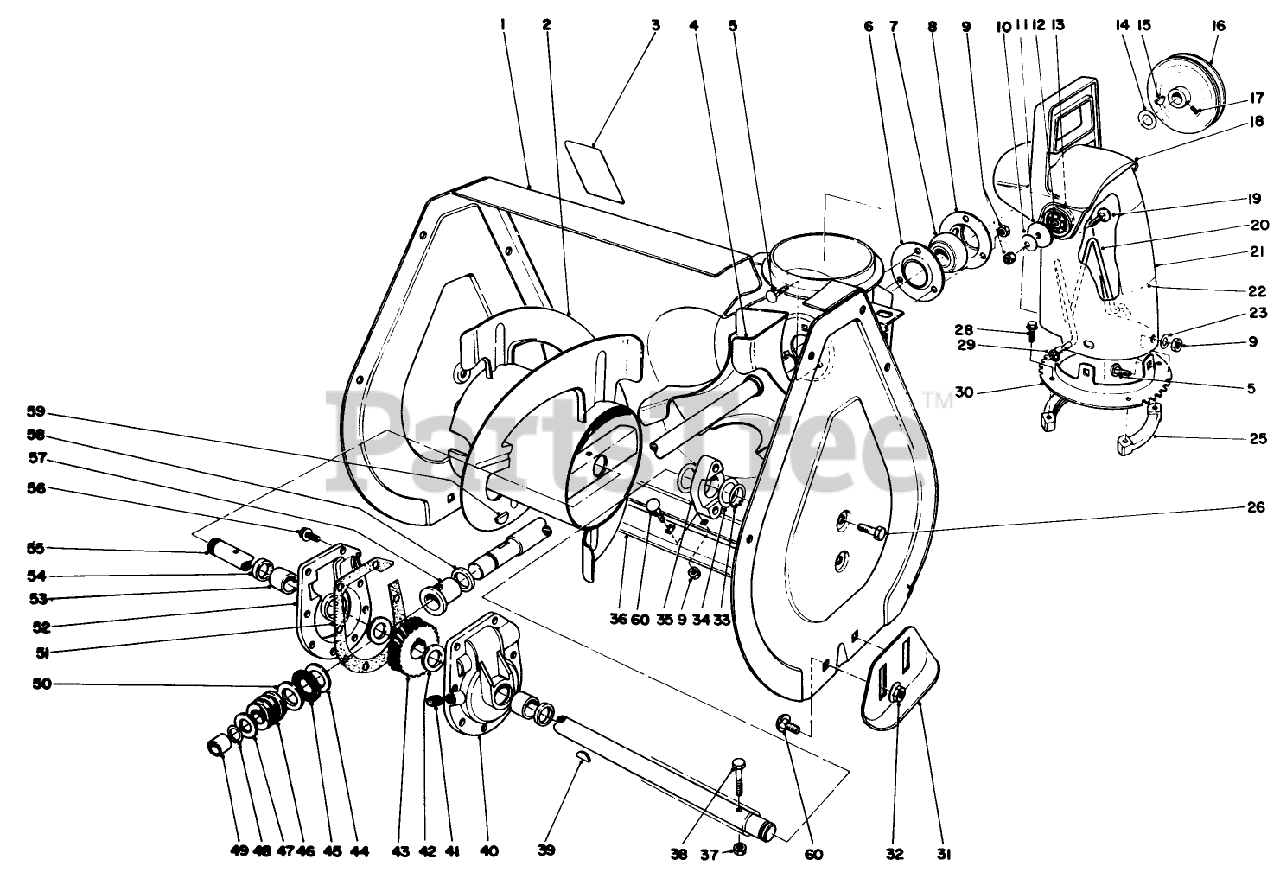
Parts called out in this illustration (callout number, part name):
1	Housing-Auger (Incl. Ref. #3)
2	Auger R.H.
3	DECAL-WARNING, AUGER
4	Shaft & Impeiler
5	SCREW-CARR
6	Flange Bearing-Front
7	BEARING-BALL
8	Flange Bearing-Rear
9	NUT-LOCK, NI
10	WASHER-BELLEVILLE
11	WASHER-FLAT
12	PLATE-FRICTION
13	WASHER-RUBBER
14	WASHER
15	KEY-WOODRUFF
16	PULLEY
17	SCREW-SET, SQH
18	CHUTE-DEFLECTOR
19	SCREW-CARR
20	WIRE-CHUTE
21	Chute Discharge (Incl. Ref. #22) (Model 38052)
21	Chute Discharge (Incl. Ref. #22) (Model 38054)
22	Decal-Danger
22	DECAL-DANGER DISCH.
23	WASHER-PLAIN
25	RING-CHUTE, RETAINER
26	SCREW-HWHTF
28	SCREW-SPECIAL
29	NUT-PUSH
30	Chute Ring
31	Skid
32	NUT-HF
33	RING-RETAINING
34	WASHER
35	BEARING-AUGER
36	Blade-Scraper
37	NUT-LOCK, NI
38	SCREW-HH
39	KEY-WOODRUFF
40	Gear Case-L.H.(Incl. Ref. #53 & 54)
41	PLUG-PIPE, SQH
42	WASHER-THRUST
43	Gear
44	WASHER-THRUST
45	BEARING-THRUST
47	WASHER-THRUST
48	Ring-Snap
49	BUSHING
50	WASHER-THRUST
51	GASKET-CASE, GEAR
52	Gear Case-R.H. (Incl. Ref. #53 & 54)
53	BUSHING
54	SEAL-OIL
55	AUGER SHAFT
56	SCREW-TAPTITE
57	BUSHING-INPUT
58	RING-QUAD
59	KEY-WOODRUFF
60	BOLT-CARR
